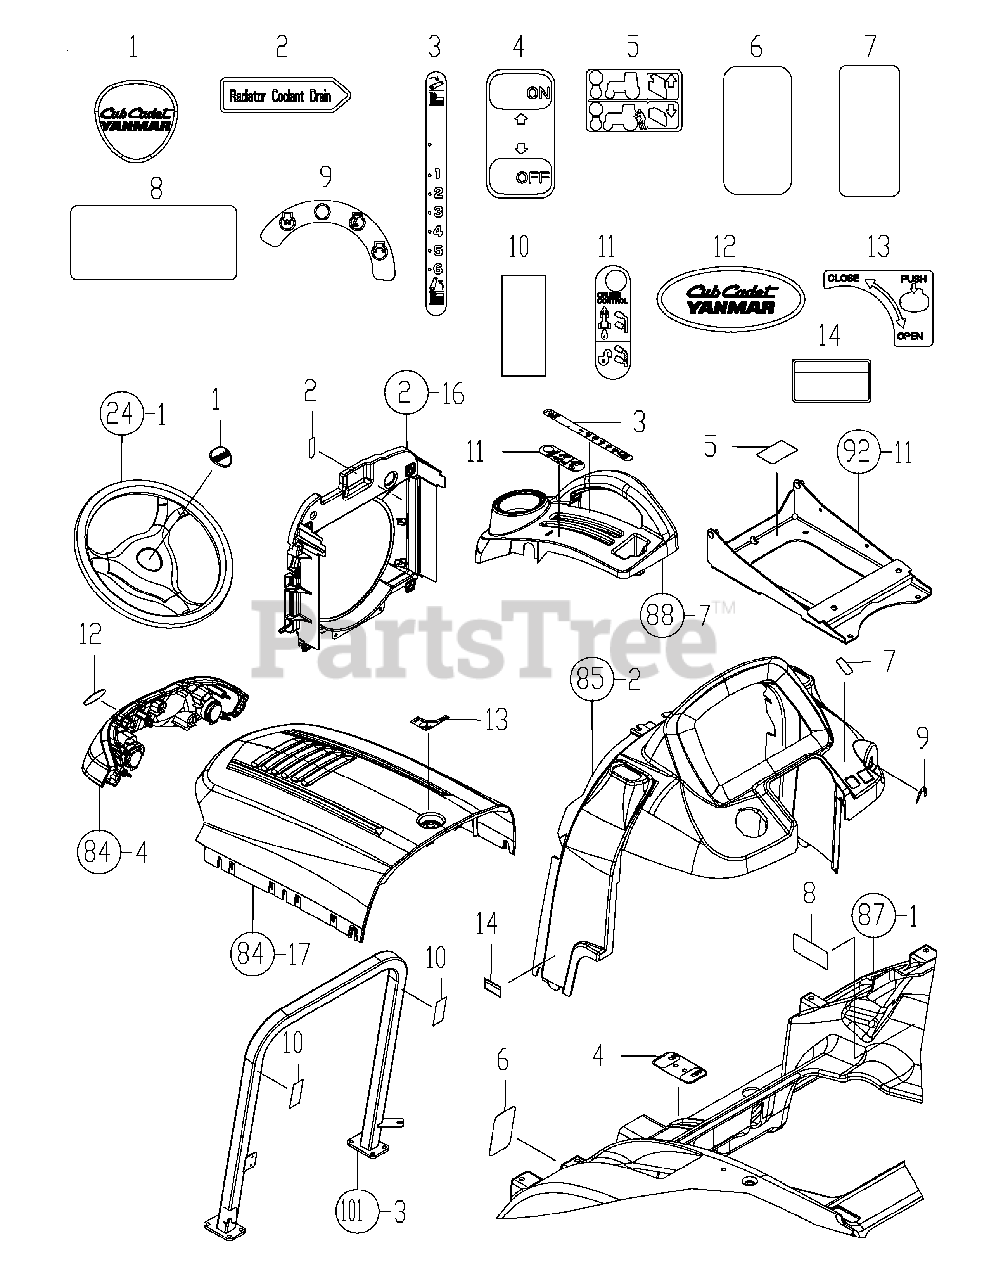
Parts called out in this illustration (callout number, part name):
1	LABEL, STEERING WHEEL
3	LABEL, POSITION
4	LABEL, LEVER 4WD
5	LABEL, LEVER VALVE
6	LABEL, DIFF LOCK
7	LABEL, ACCELERAT. LVR.
9	LABLE, START SWITCH
10	TAPE, REF.50X115
11	LABEL, CRUISE CONTROL
12	LABEL, CENTER LOGO
13	LABEL, HOOD OPEN
14	LABEL, FUEL OIL
